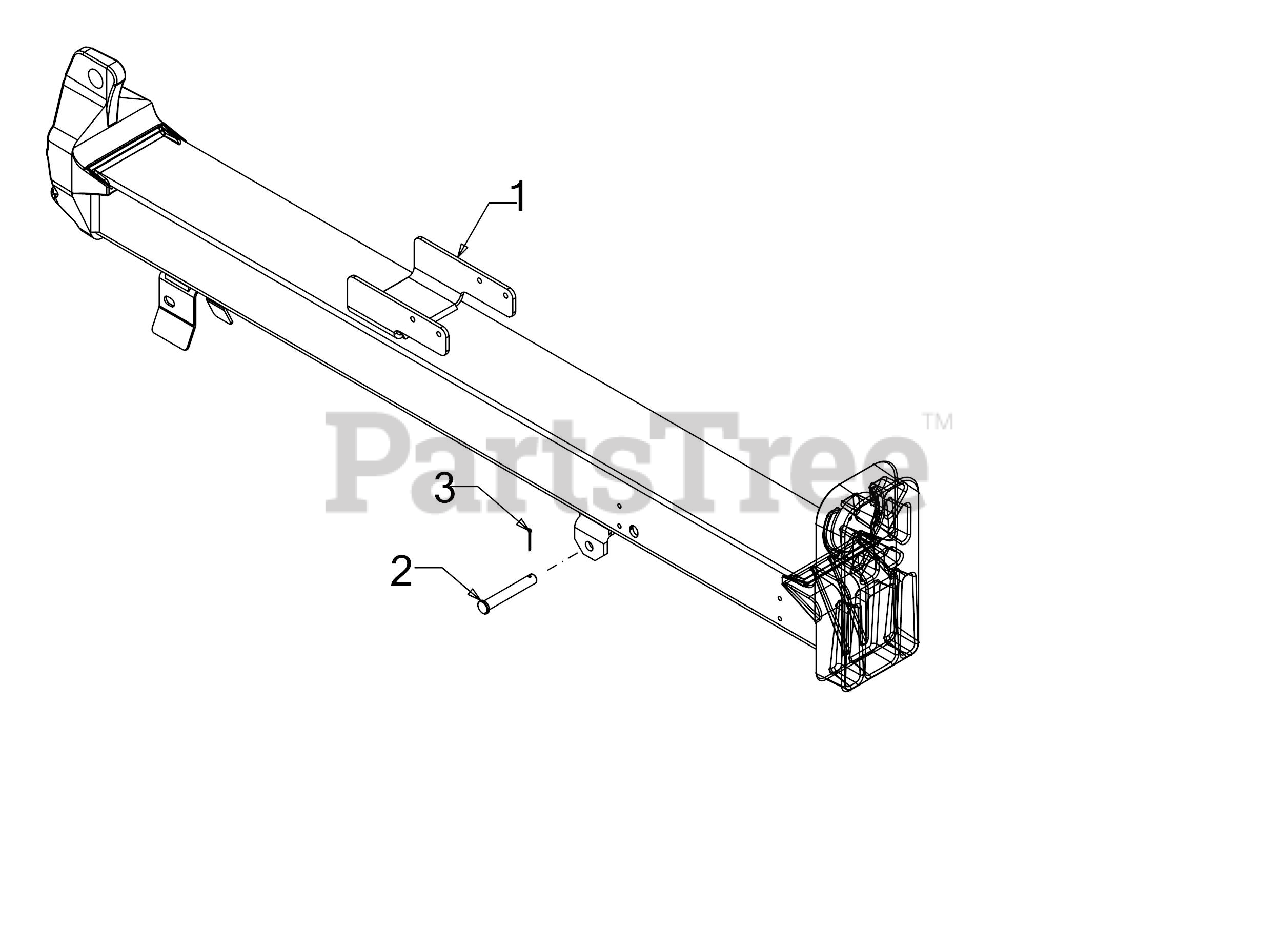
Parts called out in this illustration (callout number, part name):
1	BEAM ASSEMBLY
2	CLEVIS PIN .625 x 4.25
3	COTTER PIN
